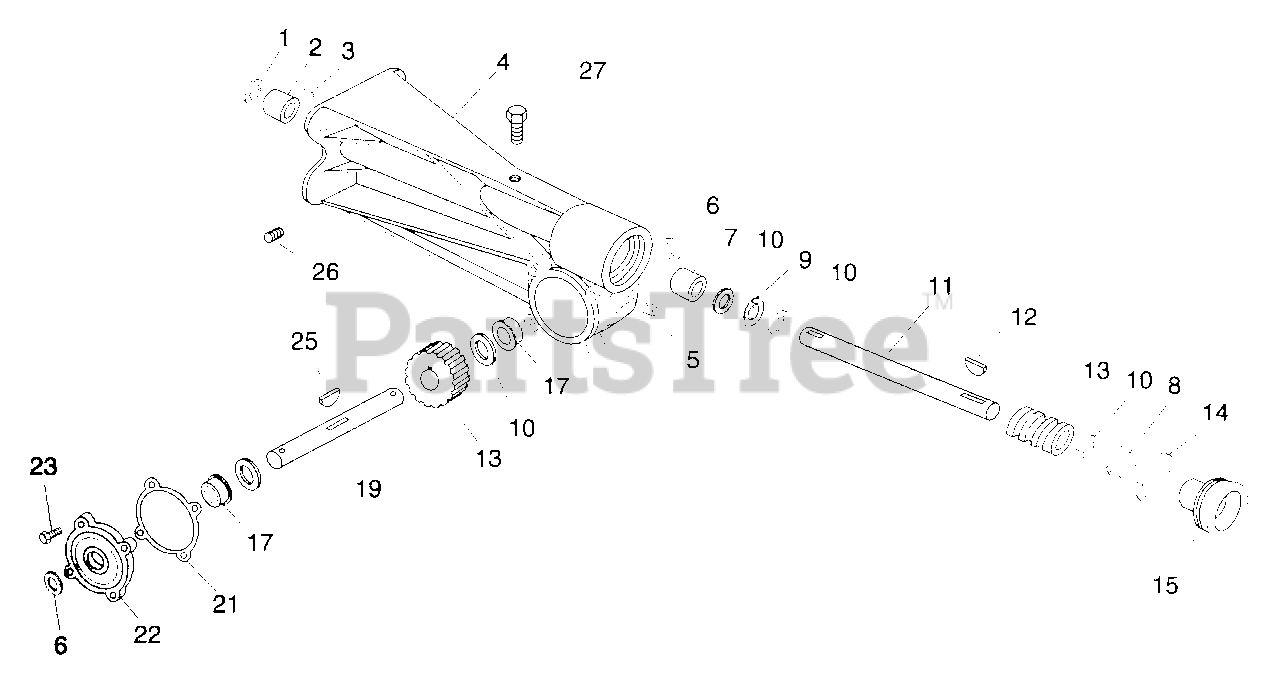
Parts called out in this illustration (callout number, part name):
1	SEAL .750X1.000X.125
2	BSHG-SLV .750X1.000X1.000
3	KEY-WDRF .188X.875X.375 SAE11
4	GEARCASE - ALUMINUM
5	PIPE PLUG
6	SEAL .750X1.980X.375
7	BSHG-SLV .750X1.000X.750
8	BSHG-FLG .750X1.000X.750X1.132
9	BRG-N THRST .754X1.24X.078
10	WSHR-HDND-THRST .755X1.40X.062
11	WORM SHAFT
12	KEY-FTHR .188X1.38X.188
13	WORM AND WORM GEAR SERVICE
15	ADJUSTMENT PLUG
17	BSHG-FLG .750X1.250X.750X1.375
19	TINE SHAFT
23	@SCR-TAP .31-18X1.00 HWH TR YZ
25	KEY-WDRF .188X.625X.25 SAE 61
26	BREATHER
27	@SCR-TAP .38-16X.50 HWH TR YWZ
